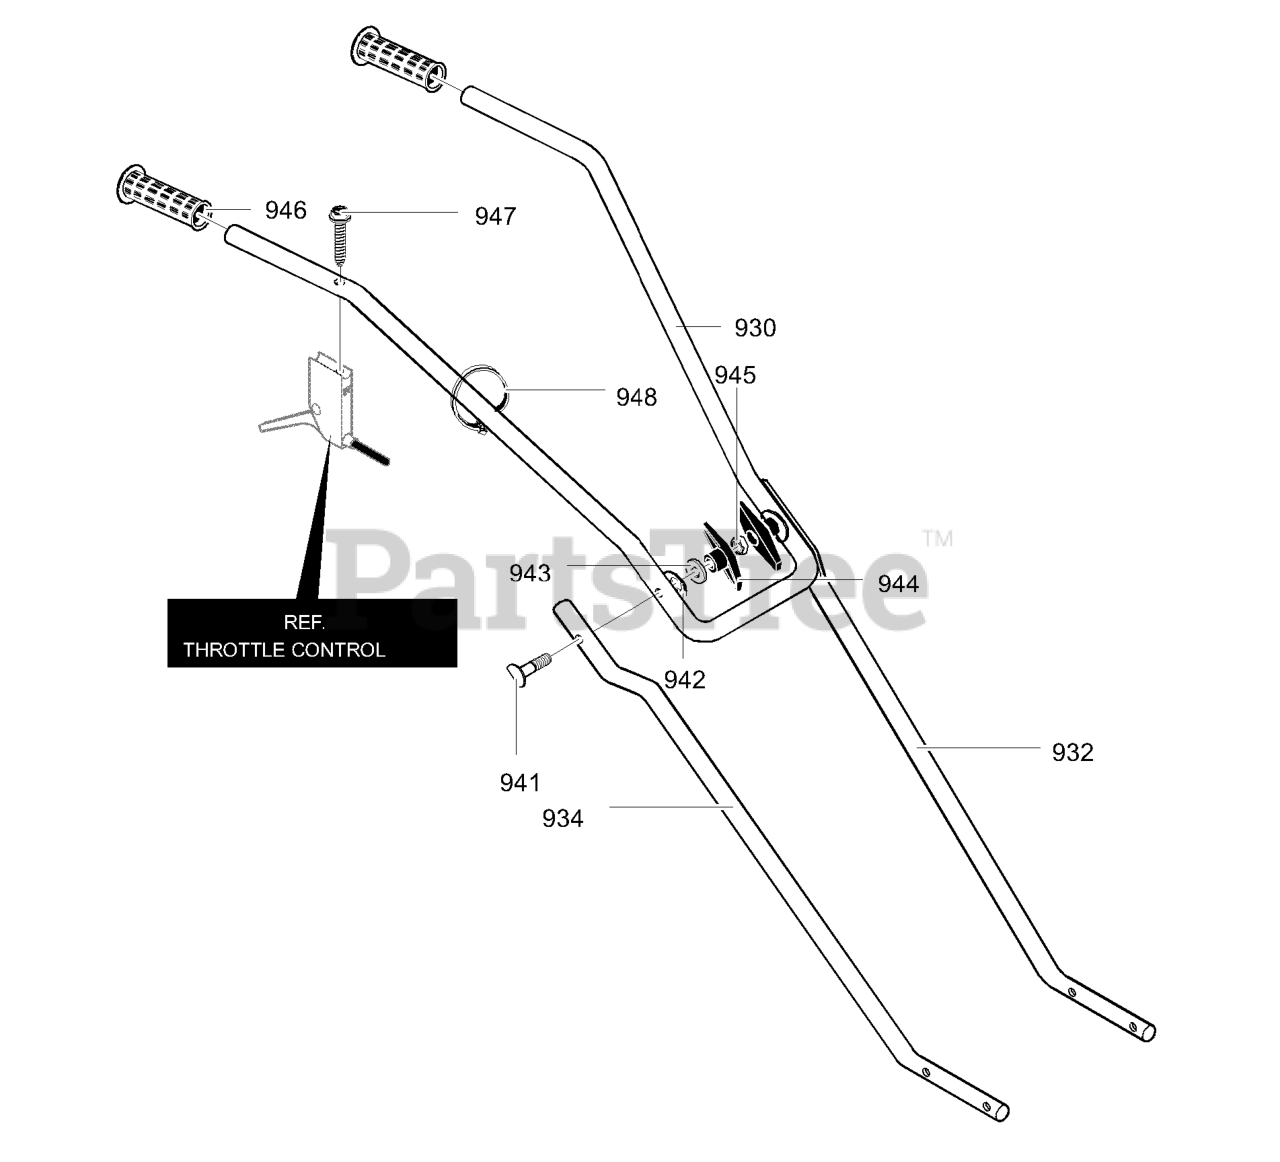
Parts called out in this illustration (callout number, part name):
930	Upper Handle
932	Lower Handle LH
934	Lower Handle RH
941	Bolt 5/16-18x1.63
942	Formed Washer
943	Flat washer
944	T Knob
945	Nut, 5/16-18
946	Hand Grip
948	Cable Tie
